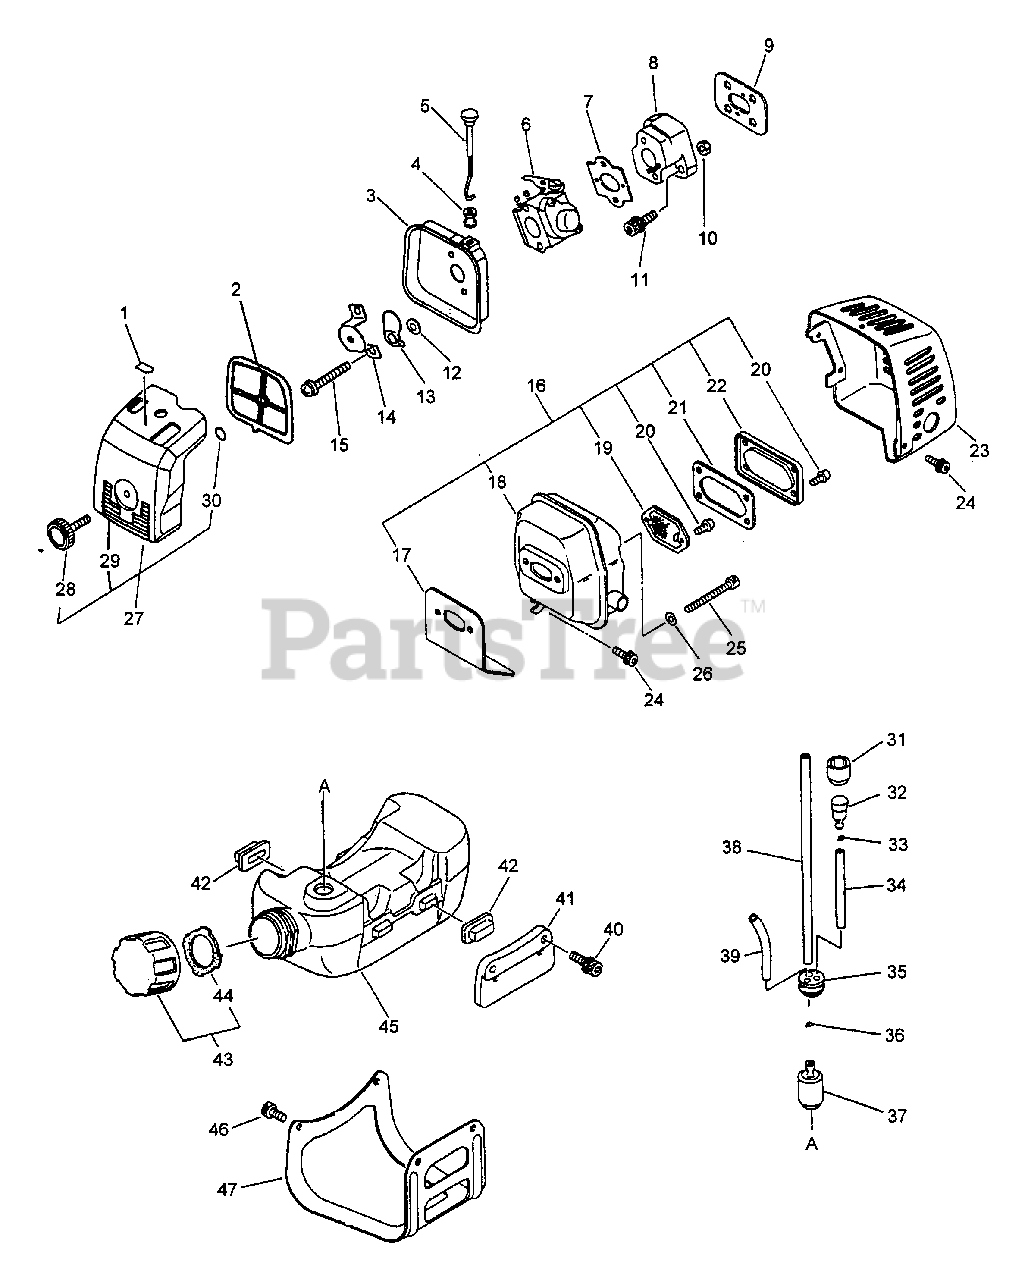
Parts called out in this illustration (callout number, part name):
1	LABEL, CHOKE
2	FILTER, HEAVY-DUTY AIR
3	CASE, AIR FILTER
4	GROMMET, CHOKE
5	ROD, CHOKE
6	CARBURETOR - WT-333
6	CARBURETOR - WT-344
7	GASKET, CARBURETOR
8	INSULATOR, INTAKE
9	GASKET, INTAKE
10	NUT M5
11	BOLT 5×25
12	WASHER 5.2×8×0.8T
13	SHUTTER, CHOKE
14	PLATE, PREVENT
15	BOLT 5×57
16	MUFFLER ASSY
17	GASKET, MUFFLER
18	MUFFLER
20	SCREW 4×10
21	GASKET, EXHAUST
22	LID, MUFFLER
23	COVER, MUFFLER
24	BOLT 5×12
25	BOLT 5×60
26	WASHER, FLAT 5.5×10×0.8
27	AIR FILTER COVER ASSY
28	THUMBSCREW
29	COVER, AIR FILTER
30	O-RING 3
31	HOLDER, VENT
32	VENT ASSY
34	PIPE, VENT - 3×5×50
35	GROMMET, FUEL
36	CLIP 6 MM
37	FILTER, FUEL
38	PIPE, FUEL 3x-5x-180
39	PIPE, FUEL RETURN 3×6×90 MM CLEAR
40	BOLT 5×20
41	BRACKET, FUEL TANK
42	CUSHION, FUEL TANK
43	CAP ASSY, FUEL
44	GASKET, FUEL CAP
45	TANK, FUEL
46	BOLT 5×12
47	GUARD, FUEL TANK
